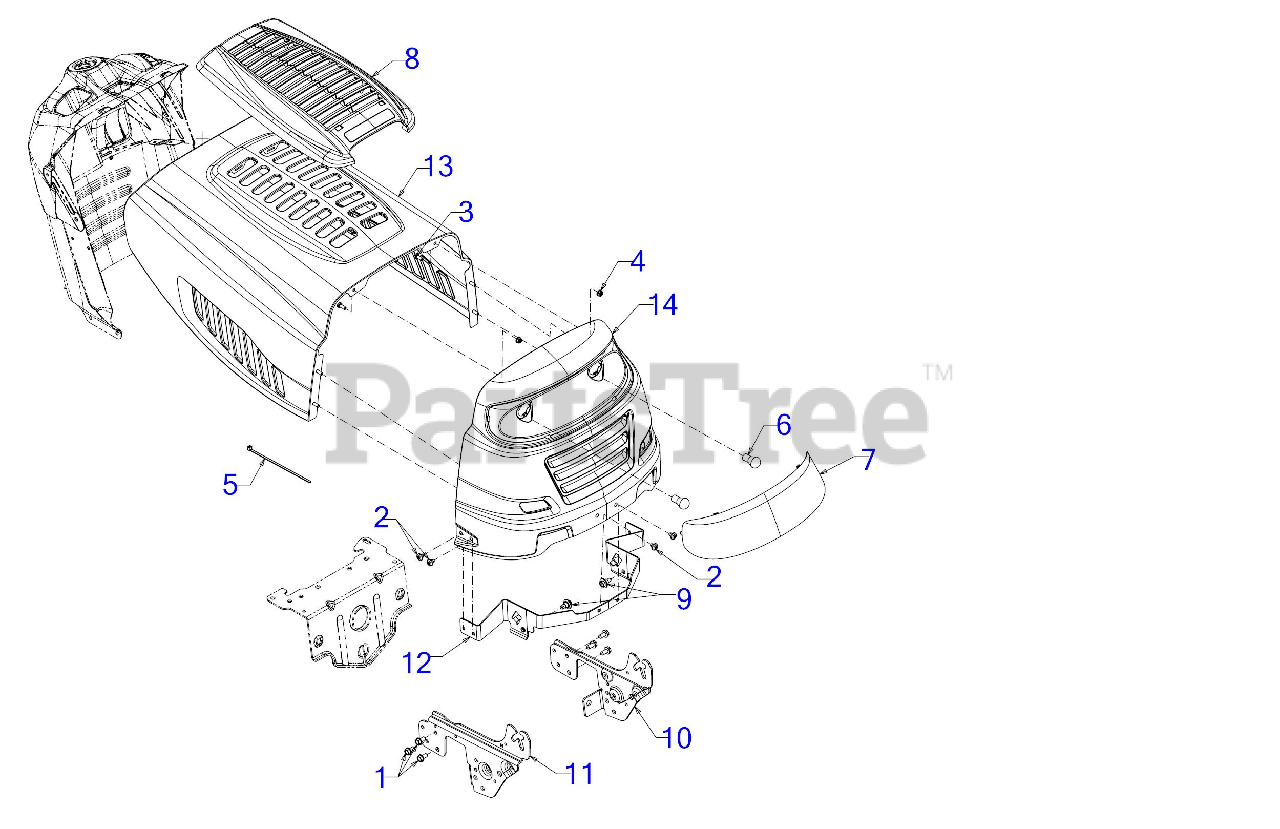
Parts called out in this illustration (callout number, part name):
1	SCREW 5/16-18 x .750
2	SCREW 5/16-18 x .375
3	SCREW 1/4-20 x .620 GR5
4	FLANGE LOCK NUT
5	7" CABLE TIE
6	MINIATUURE BULB 12V
7	GRILL LENS
8	HOOD COVER
9	SHOULDER SCREW .43X.29X5/16-18 TT
12	HOOD PIVOT BRACKET
